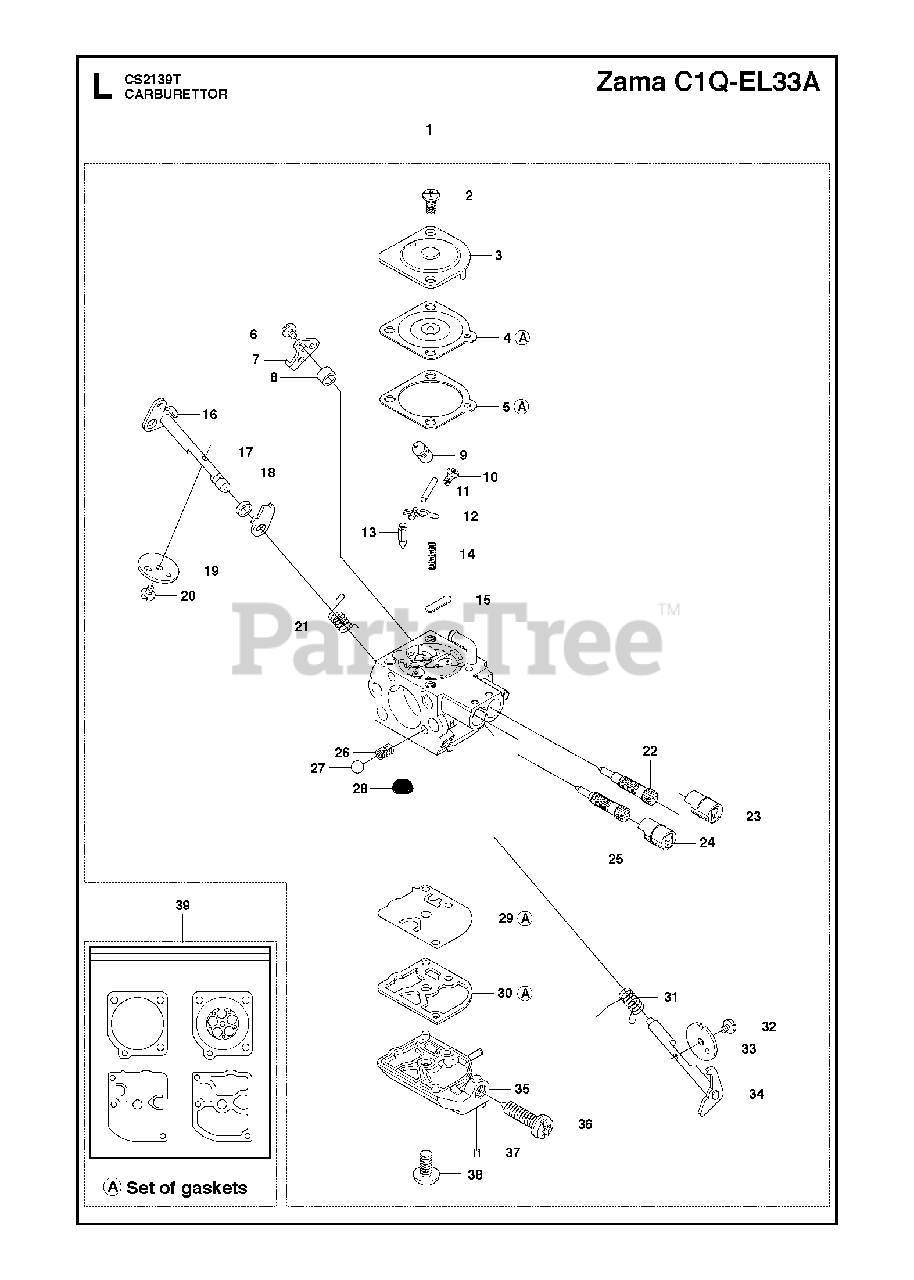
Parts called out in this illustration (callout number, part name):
1	CARBURETOR
2	SCREW
3	COVER
4	DIAPHRAGM
5	GASKET
6	SCREW
7	ARM
8	SPACER
9	NOZZLE
10	SCREW
11	PIN FULCRUM
12	LEVER
13	INLET NEEDLE
14	SPRING
15	PLUG
16	SHAFT
17	WASHER
18	ARM
19	CHOKE FLAP
20	SCREW
21	SPRING
22	IDLE SCREW
23	LIMITER CAP KIT
24	LIMITER CAP KIT
25	SCREW
26	SPRING
27	BALL
28	STRAINER
29	PUMP DIAPHRAGM
30	GASKET
31	SPRING THROTTLE
32	SCREW
33	THROTTLE FLAP
34	SHAFT
35	COVER
36	SCREW
37	PLUG
38	SCREW
39	GASKET KIT (ZAMA GND39)
